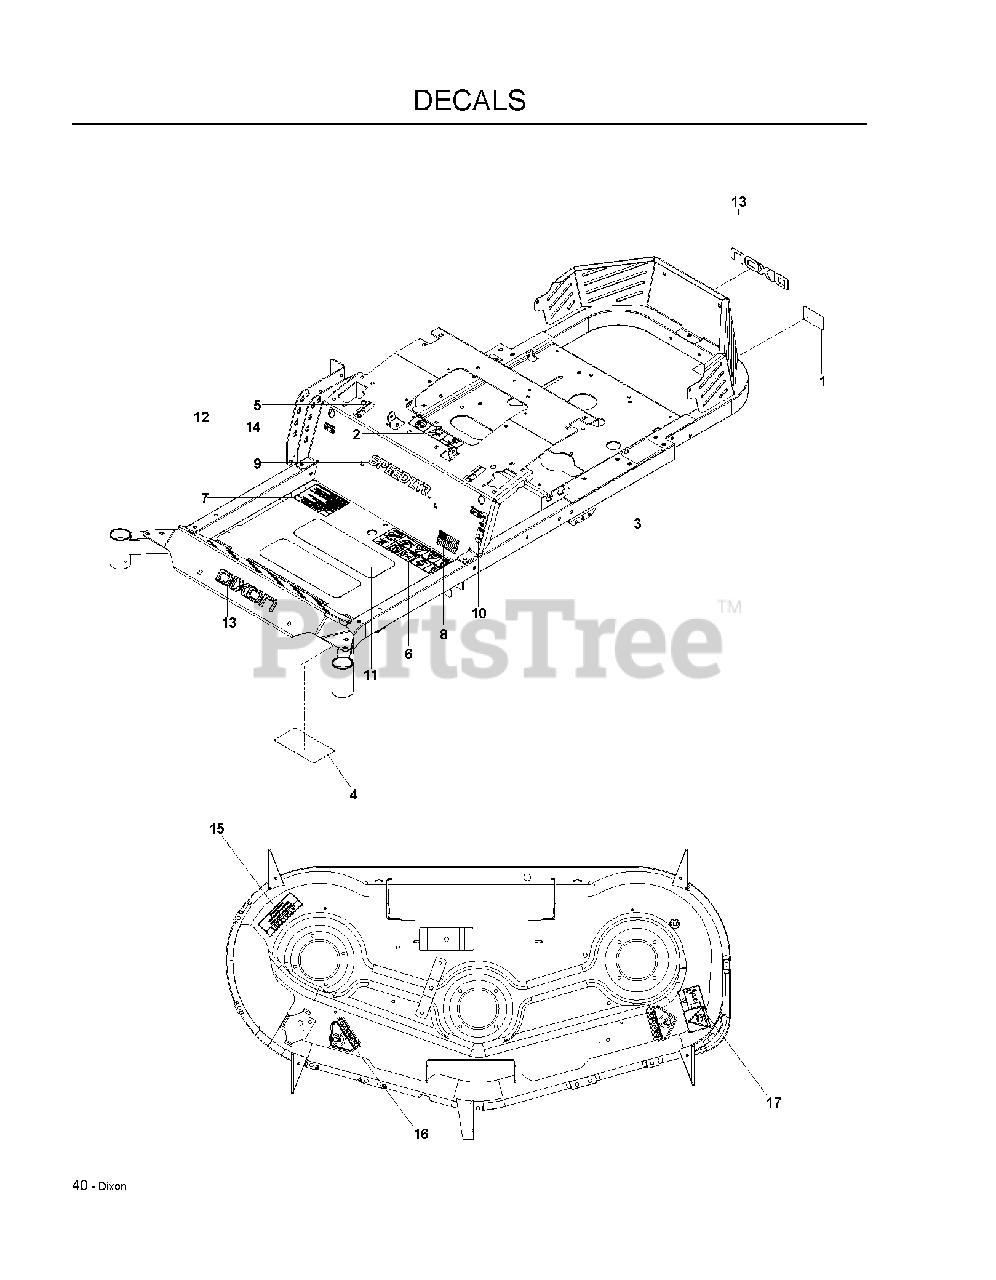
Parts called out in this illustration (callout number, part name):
1	DECAL, PROP. 65
2	DECAL, BATTERY
3	DECAL, DO NOT MOUNT
4	DECAL, SERVICE
5	DECAL, MOTION CONTROL
6	DECAL, SAFETY WARNING
7	DECAL, WARNING
8	DECAL, FLAG
9	DECAL, SPEEDZTR, 8"
10	DECAL, PARK BRAKE
11	ANTI-SKID PAD
12	DECAL, HEIGHT
13	DECAL, DIXON LOGO, DOMED
14	DECAL, F.S.T.
15	DECAL, DANGER
16	DECAL, CPSC
17	DECAL, EURO SEVERING
